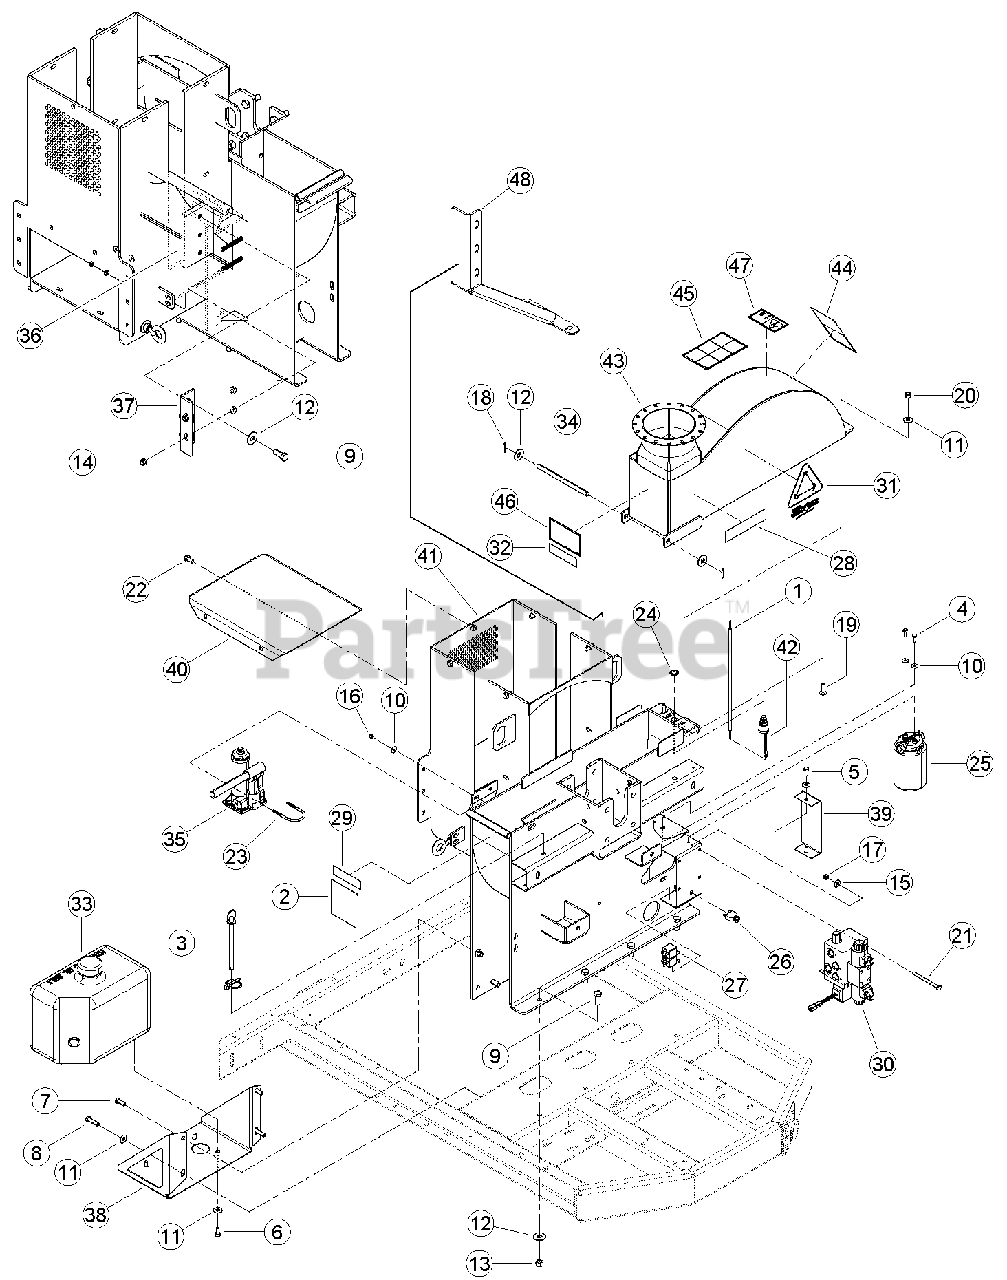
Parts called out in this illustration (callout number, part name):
1	ASSY, ENGINE KILL WIRE
2	DECAL, 111 DB (EURO MODELS)
3	PIN, HITCH 1/2 X 6-1/2 W/ PIN
4	BOLT, 1/4 X 3/4 HEX HD GR5 ZP
5	BOLT, 5/16 X 3/4 HEX HD GR5 ZP
6	BOLT, 3/8 X 3/4 HEX HD GR5 ZP
7	BOLT, 3/8 X 1 HEX HD GR5 ZP
8	BOLT, 3/8 X 1-1/2 HCS GR5 ZP
9	BOLT, 1/2 X 1-1/4 HHCS GR5 NC ZP
10	WASHER, 1/4 FLAT ZP
11	WASHER, 3/8 FLAT ZP
12	WASHER, 1/2 FLAT ZP
13	NUT, 1/2 CENTERLOCK GRB ZP
14	NUT, 3/8 SERR FLANGE NC ZP
15	WASHER, 5/16 FLAT ZP
16	NUT, 1/4 NE NYLOCK ZP
17	NUT, 5/16 NE NYLOCK ZP
18	PIN, 1/8 X 1 ZP COTTER
19	BOLT, 3/8 X 1-1/4 CRG GR5 NC ZP
20	NUT, 3/8 NE NYLOCK ZP
21	BOLT, 5/16 X 4 HHCS GR5 ZP
22	BOLT, 3/8 X 3/4 SERR FLANGE
23	U-BOLT, 1/4 X 1-1/2 PIPE
24	NUT, 5/8-32 JAM
25	FILTER, SPIN-ON
26	CIRCUIT BREAKER, 10 AMP RESETTABLE
27	RELAY, 12V SPDT W/FLANGE
28	DECAL, MODEL CH6730H
29	DECAL, CH6730H CE INFORMATION (CE COMPLIANT MODELS)
30	ASSEMLBY, CHIPPER FLOW VALVE
31	DECAL, CHIP IT
32	DECAL, ATLANTIC BRIDGE LTD INFO (CE COMPLIANT MODELS)
33	TANK, HYDRAULIC
34	SHAFT, CHIPPER TOP PIVOT
35	JACK, HYDRAULIC 2 TON
36	PLATE, CHIPPER ANVIL
37	WELDMENT, BLOCK ADJUSTOR
38	BRACKET, HYDRAULIC TANK
39	COVER, CHIPPPER SHAFT
40	WELDMENT, TOPROLLER COVER
41	WELDMENT, 6 IN. CHIPPER HOUSING MAIN
42	ASSEMLBY, SEALED SWITCH
43	ASSEMBLY, CHIPPER COVER W/ DECALS, SERVICE PART
44	DECAL, KNIFE ACCESS ISO
45	DECAL, OPERATING INSTRUCTIONS ISO
46	DECAL, DISCHARGE ISO
47	DECAL, MAINTENANCE ISO
48	FEED ROLLER SUPPORT
